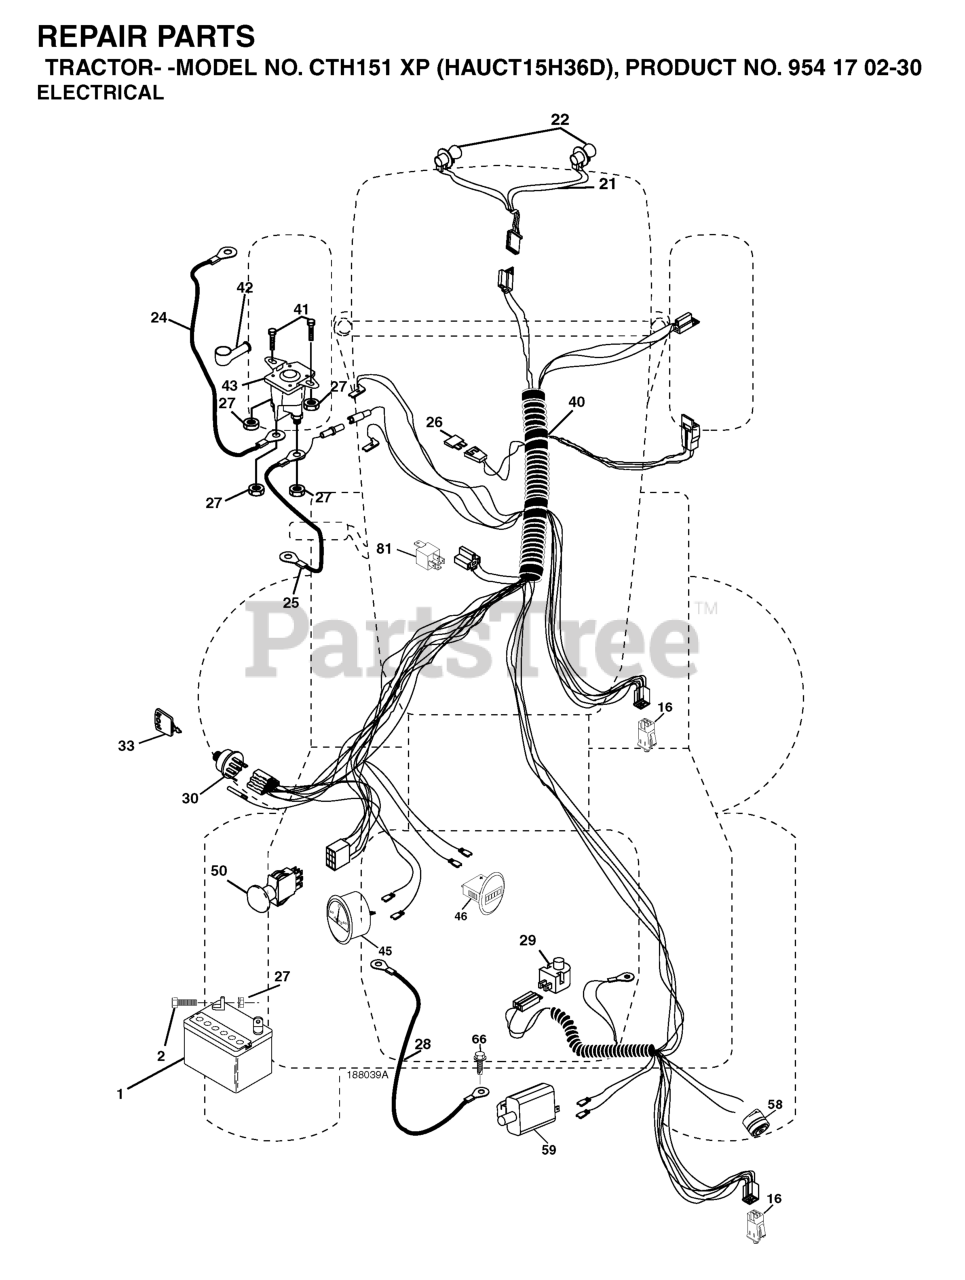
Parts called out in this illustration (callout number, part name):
1	BATTERY 12V .35 AMP
2	BOLT.HEX.1/4.X.3/4.DICHROMATE
16	SWITCH INTERLOOK PUSH-IN
21	HARNESS.W/LIGHT SOCKET
24	BATTERY CABLE GT
25	CABLE BATTERY
26	FUSE 20AMP
27	NUT
28	CABLE GROUND
29	RP.SWITCH.PLUNGER.NC.GRAY
30	IGNITION SWITCH
33	KEY MLD GEN DELTA
41	BOLT
42	TERMINAL COVER
43	SOLENOID
45	RP AMMETER.ROUND.SILVER.DELTA
46	RP HOURMETER SNAP-IN
50	RP.PTO.SWITCH.8 TERMINAL.BLACK
58	BUZZER
59	.WITCH.FULL BAGGER.INDICATOR
66	SCREW LT
79	BULB HOLDER ASM.
81	RELAY.ASSY.T
